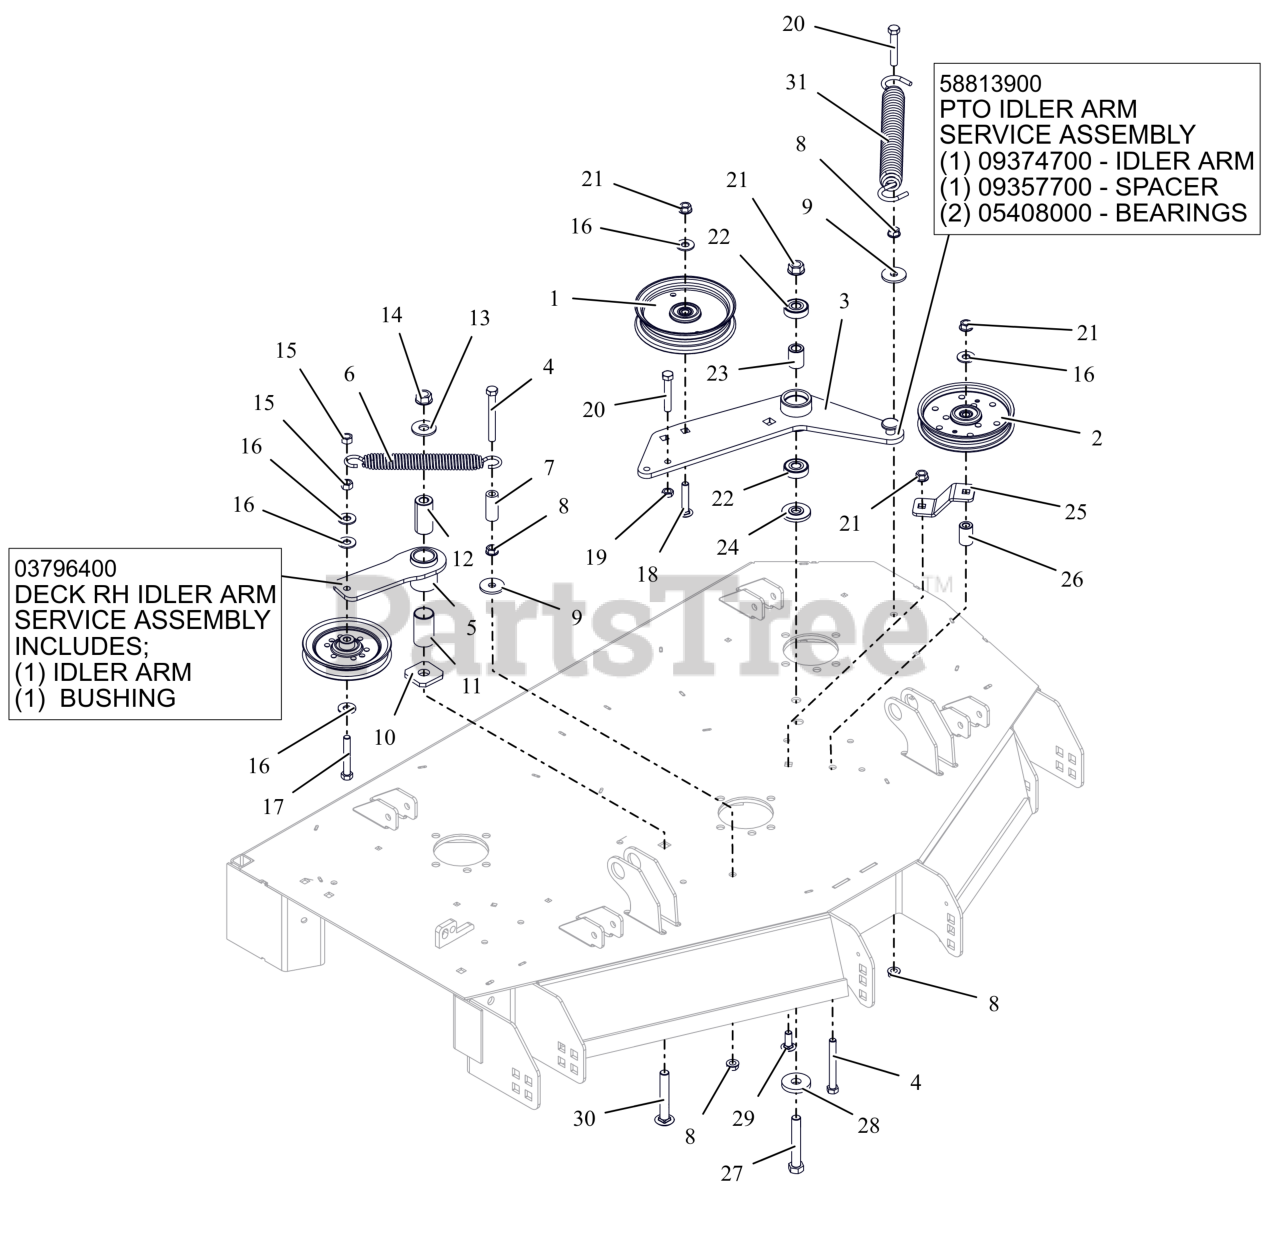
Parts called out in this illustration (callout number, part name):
1	IDLER- FLAT - 5.00" X .75"
2	IDLER- 5" FLANGED
3	WLDMT, IDLER ARM PT660
3	PTO IDLER ARM
3	SPACER .510 X .867 X 1.1485
3	BRG-BALL .500X1.38X.437
4	BLT, HEX .38-16X3.25 G5 ZCC
5	WMT, IDLER ARM - BLACK
5	ASM, IDLER ARM (DECK)
5	BSHG, 1.00X1.125X1.937
6	SPRING- EXTENSION
7	HOSE, .38 X 1.65
8	NUT, SPNLK-FLG .38-16 G5 ZCC
9	WSHR,FLT .406X1.375X.135 ZCC
10	WSHR-FLT .640X1.75X.250
11	BSHG, 1.00X1.125X1.937
12	BSHG, SPCR .502X.997X2.03 PM
13	WSHR,FLT .563X1.375X.109 ZCC
14	NUT-LK-CTR-FLG .500-13 GG ZCC
15	NUT-LK-CTR .38-16 ZC120
16	WSHR,FLT .438X1.00X.083 ZCC
17	BLT, HEX .38-16X2.50 G5 ZCC
18	BLT,RHSSN.375-16X2.00 G5 ZCC
19	NUT-JAM .375-16 G2 ZCC
20	BLT,HEX .38-16X2.25 G5 ZCC
21	NUT, FLG-CTR LK .
22	BRG-BALL .500X1.38X.437
23	SPACER .510 X .867 X 1.1485
24	SPACER, IDLER ARM
25	PTO FIXED IDLER MTG BRKT -RED
26	BUSHING, SLV .380X.750X1.190
27	BLT,HEX .50-13X3.25 G5 ZCC
28	WSHR-FL-STL 0.557X1.625X0.25 ZCC
29	BLT,RHSSN .38-16X1.00 G5 ZCC
30	BTL,RHSSN .500-13 X 3.25 G5 ZCC
31	SPRING, EXTENSION
